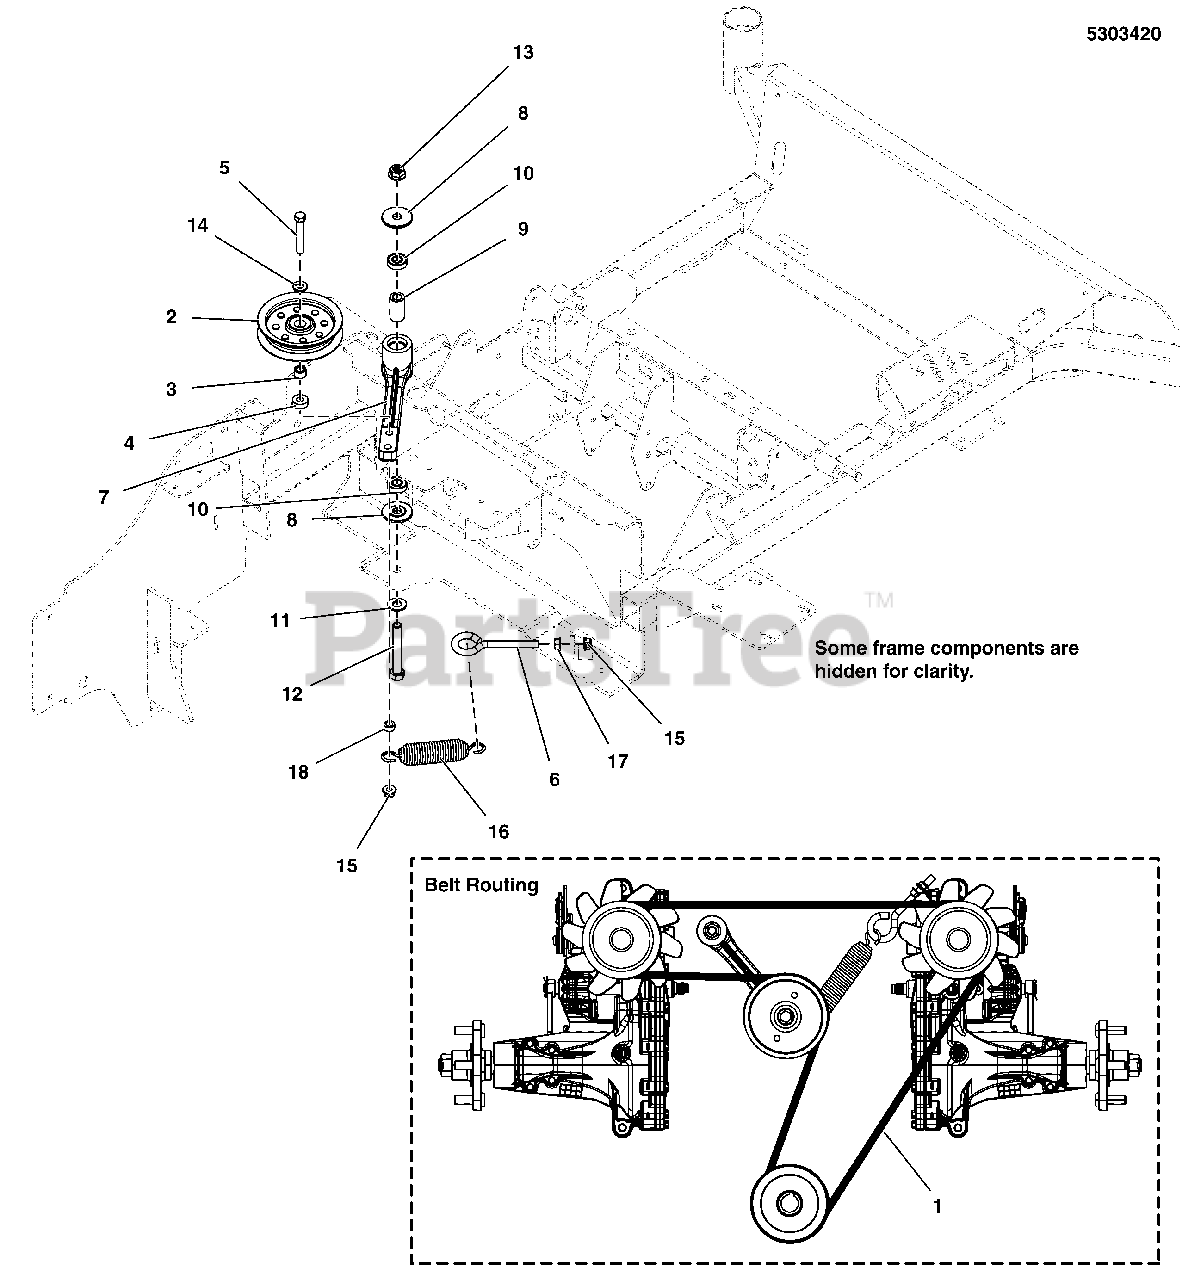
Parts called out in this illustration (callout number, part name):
1	BELT, A-SEC, 79.3"EL, ARAMID, WRPD
2	PULLEY, IDLER, 4.06OD, .669ID, .75W STL
3	INSERT, BEARING, 17MM X 12MM L
4	SPACER-0.390ID 0.90 OD 0.34 LG P'MTL YEL
5	BOLT, 3/8-16 X 2-1/2 GD5 YZ
6	EYE BOLT, 3/8-16 X 5, 2.88THRD, 1EYE, CZ
6	EYEBOLT, 3/8-16 X 8, 3 THRD, 1 EYE, CZ
7	IDLER ARM, CAST, MACHINED
8	SPACER, Idler Arm
10	BEARING, Ball
11	WASHER, 1/2 SAE
12	BOLT, 1/2-13 X 3-1/2 GD5 YZ
13	NUT, 1/2-13 HEX NYLOCK FLANGE
14	WASHER, 3/8 GD.9 FLAT
15	NUT, Hex Flange, Nylock, 3/8-16
16	SPRING, Extension
17	NUT, 3/8-16 HEX SERRATED FLANGE
18	SPACER, 0.385ID 0.623OD 0.290LG P'MTL
